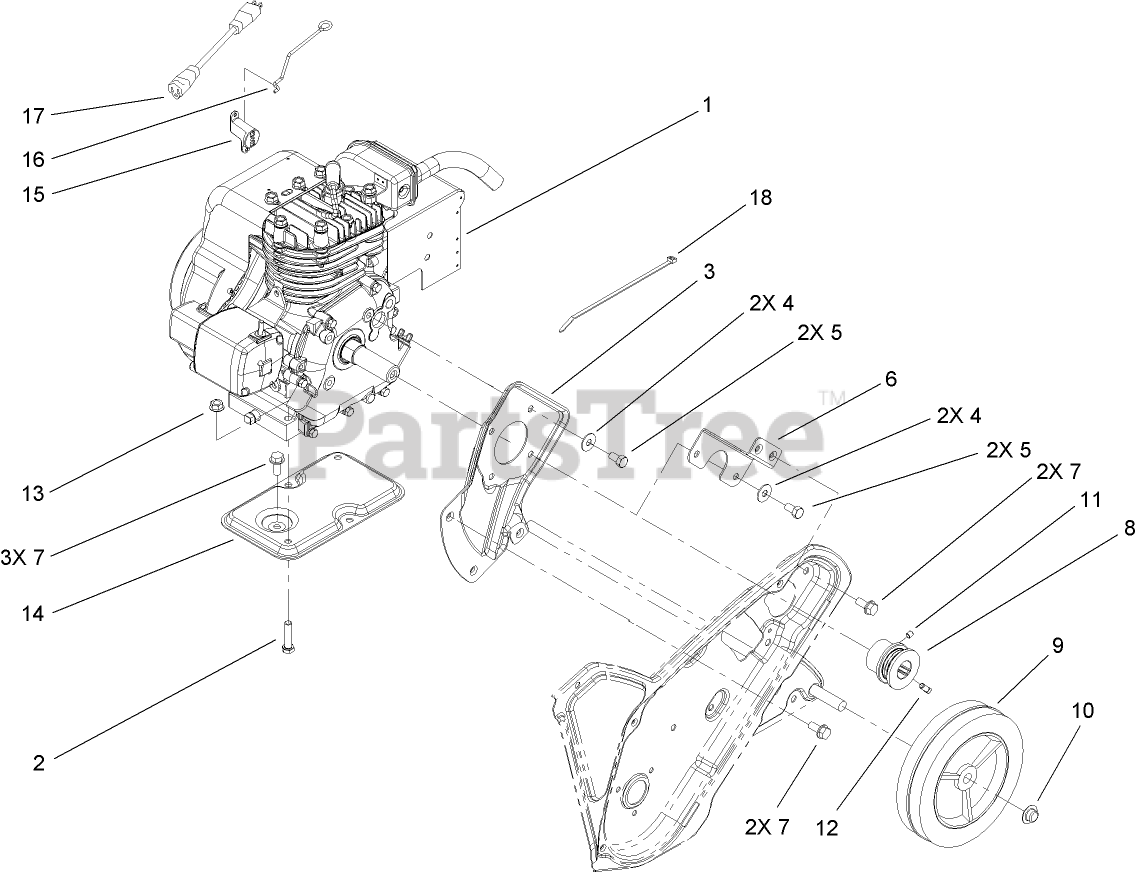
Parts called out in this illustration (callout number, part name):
1	Loose Parts Package
2	SCREW-HH
3	PLATE-ENGINE, PTO
4	WASHER-BELLEVILLE
5	SCREW-HH
6	SUPPORT-ENGINE, SIDE
7	SCREW-THD ROLL, HWH
8	PULLEY-ENGINE
9	WHEEL
10	NUT-PUSH
11	SCREW-HSH
12	SCREW-SQH
13	NUT-HF
14	SUPPORT-ENGINE
15	BELLCRANK-CHOKE, 4 STROKE
16	LINK-CHOKE KNOB, L-HEAD
17	CORD-EXTENSION (only on: 38078)
18	TIE-CABLE
